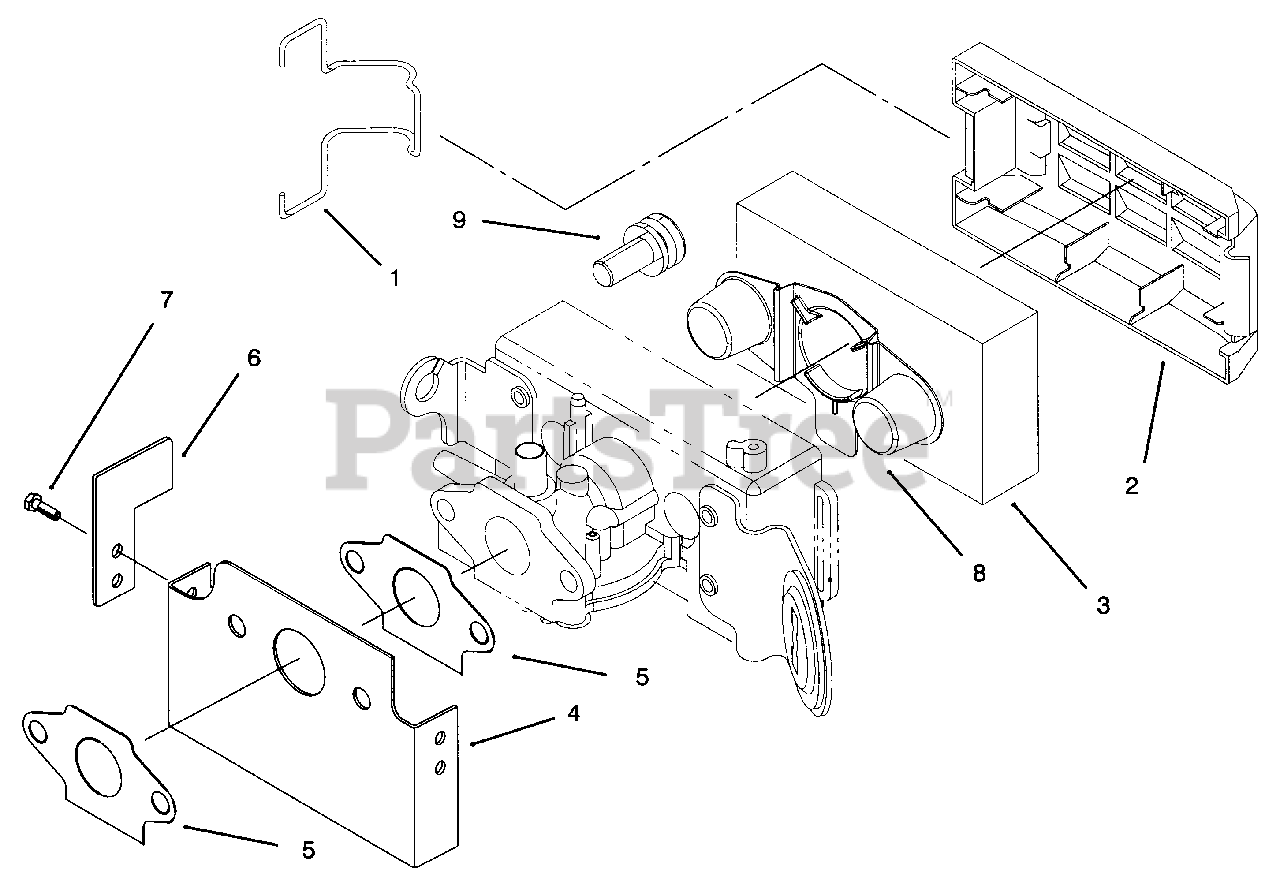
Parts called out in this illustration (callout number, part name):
1	Retainer-Cover
2	Cover-Air Filter
3	Element-Air Filter
4	Shield-Carburetor (Int'l)
5	Gasket-Carb.
6	Shield-Governor F (Int'l)
8	Shield-Fuel
